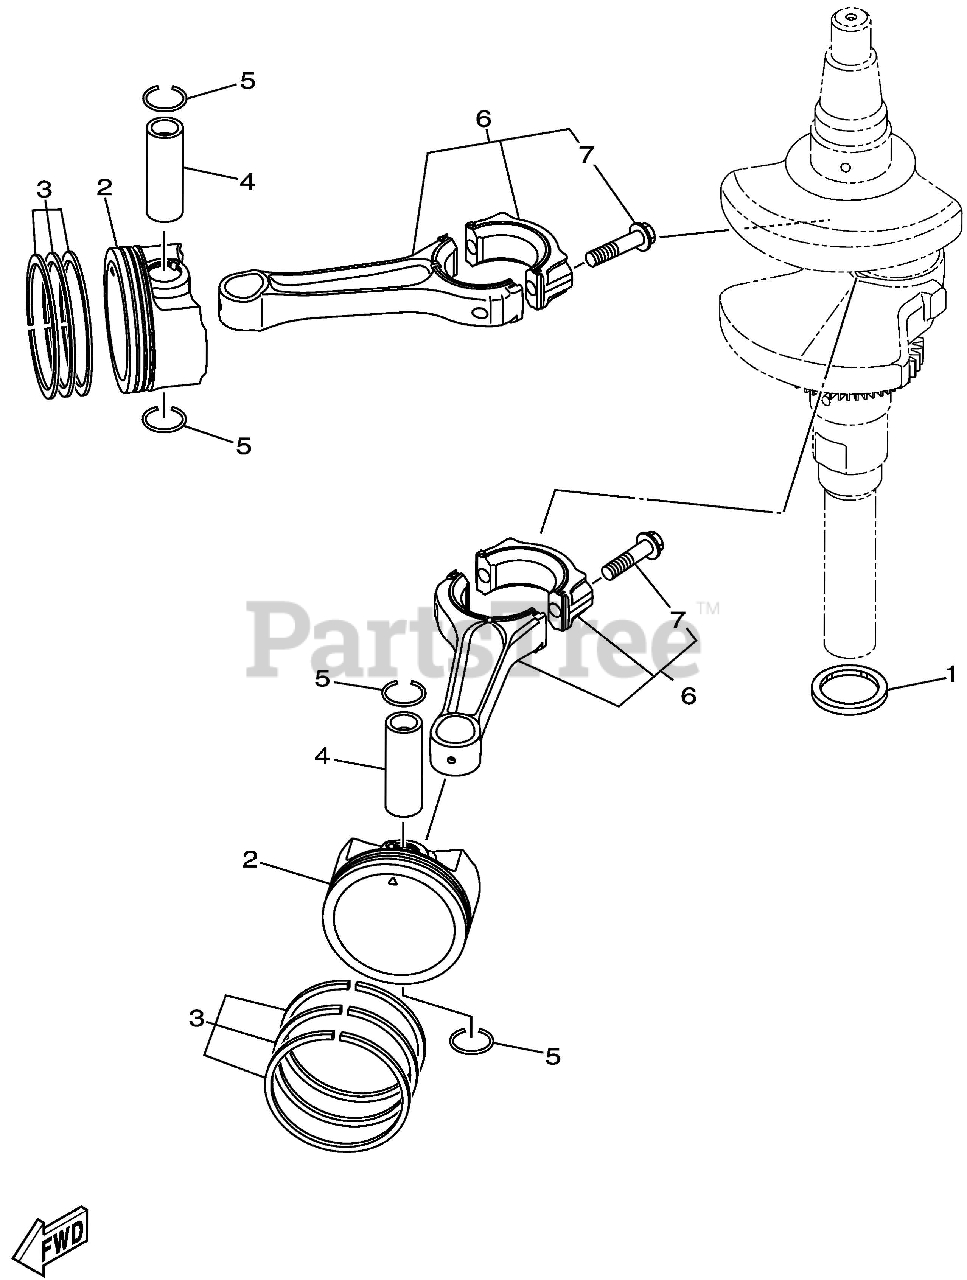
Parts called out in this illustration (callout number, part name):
2	PISTON (STD)
2	PISTON (0.25MM O/S)
2	PISTON (0.50MM O/S)
3	PISTON RING SET (STD)
3	PISTON RING SET (0.25MM O/S)
3	PISTON RING SET (0.50MM O/S)
4	PIN, PISTON
6	CONNECTING ROD ASSY
7	BOLT, CONNECTING ROD
